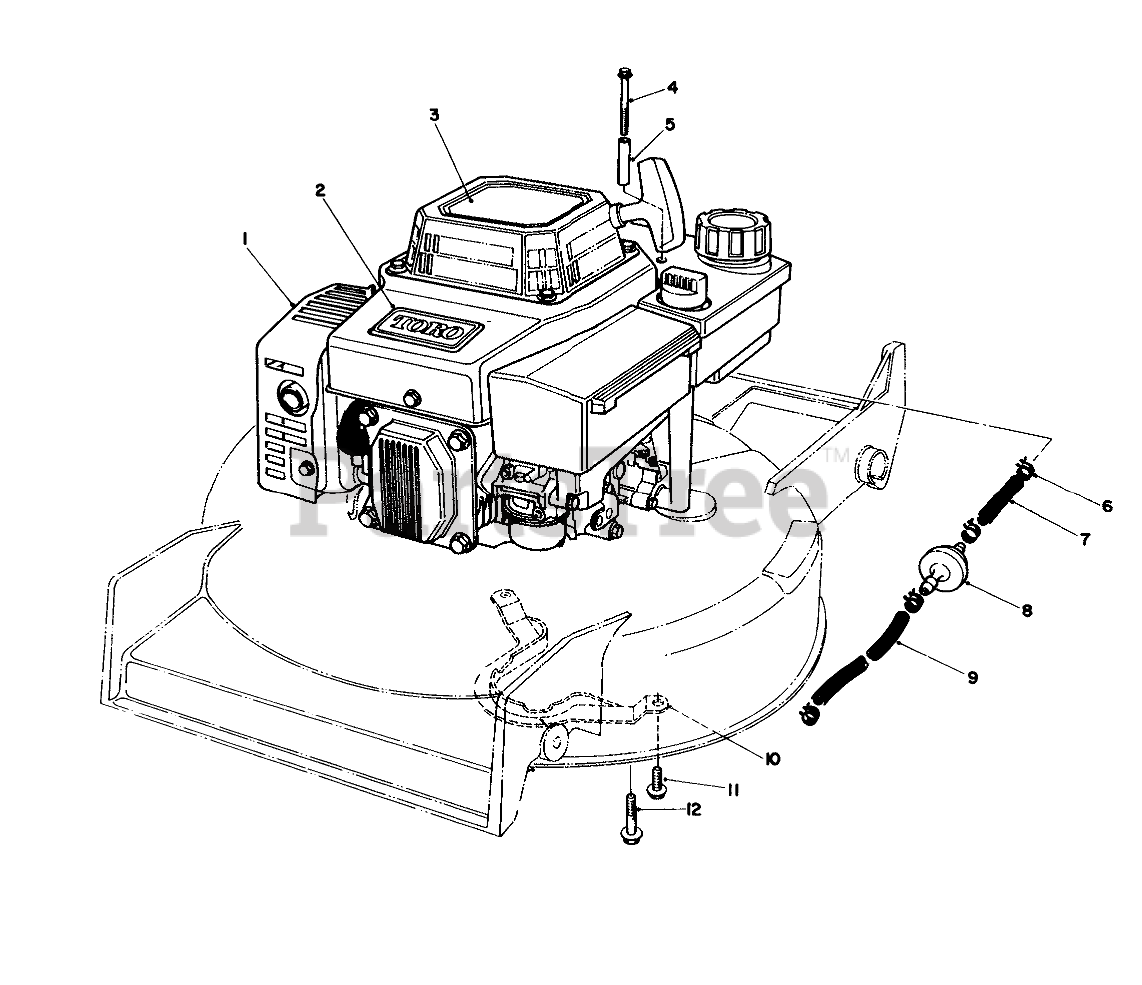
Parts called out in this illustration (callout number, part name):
1	Engine
2	TORO LOGO PLT
3	DECAL-HV INT'L
4	THRD FORMING SCREW
5	TUBULAR SPACER
6	CLAMP-FUEL LINE
7	LINE-GAS
8	FILTER-FUEL
9	HOSE-FUEL
10	BBC BELT GUIDE
11	SCREW-HWHTF
12	SCREW-HWHTF
